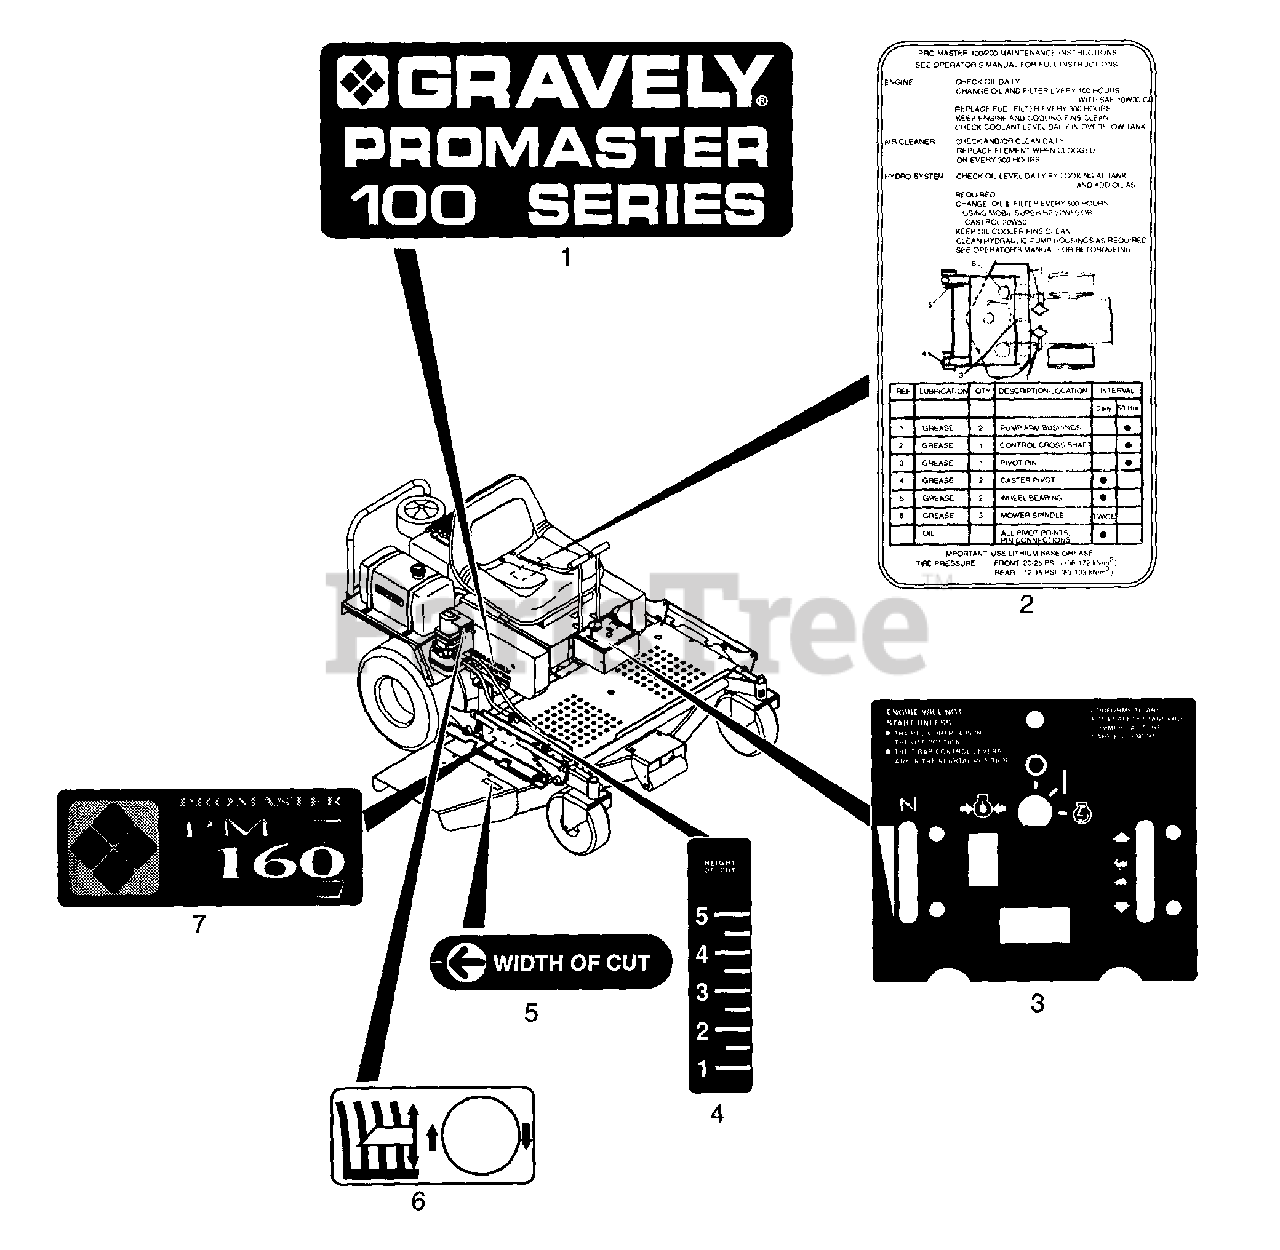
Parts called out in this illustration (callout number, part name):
1	Decal-Promaster 100
1	Decal-Gravely Logo Right-Hand
1	Decal-Gravely Logo
2	Decal-PM-100/200 Maintenance
3	Decal-Engine Panel
4	Decal-PM-100/50 Deck Lift
5	Decal Set for Mower Decks
6	Decal-Cutting Height Adjustment
7	Decal-PM160Z Logo
